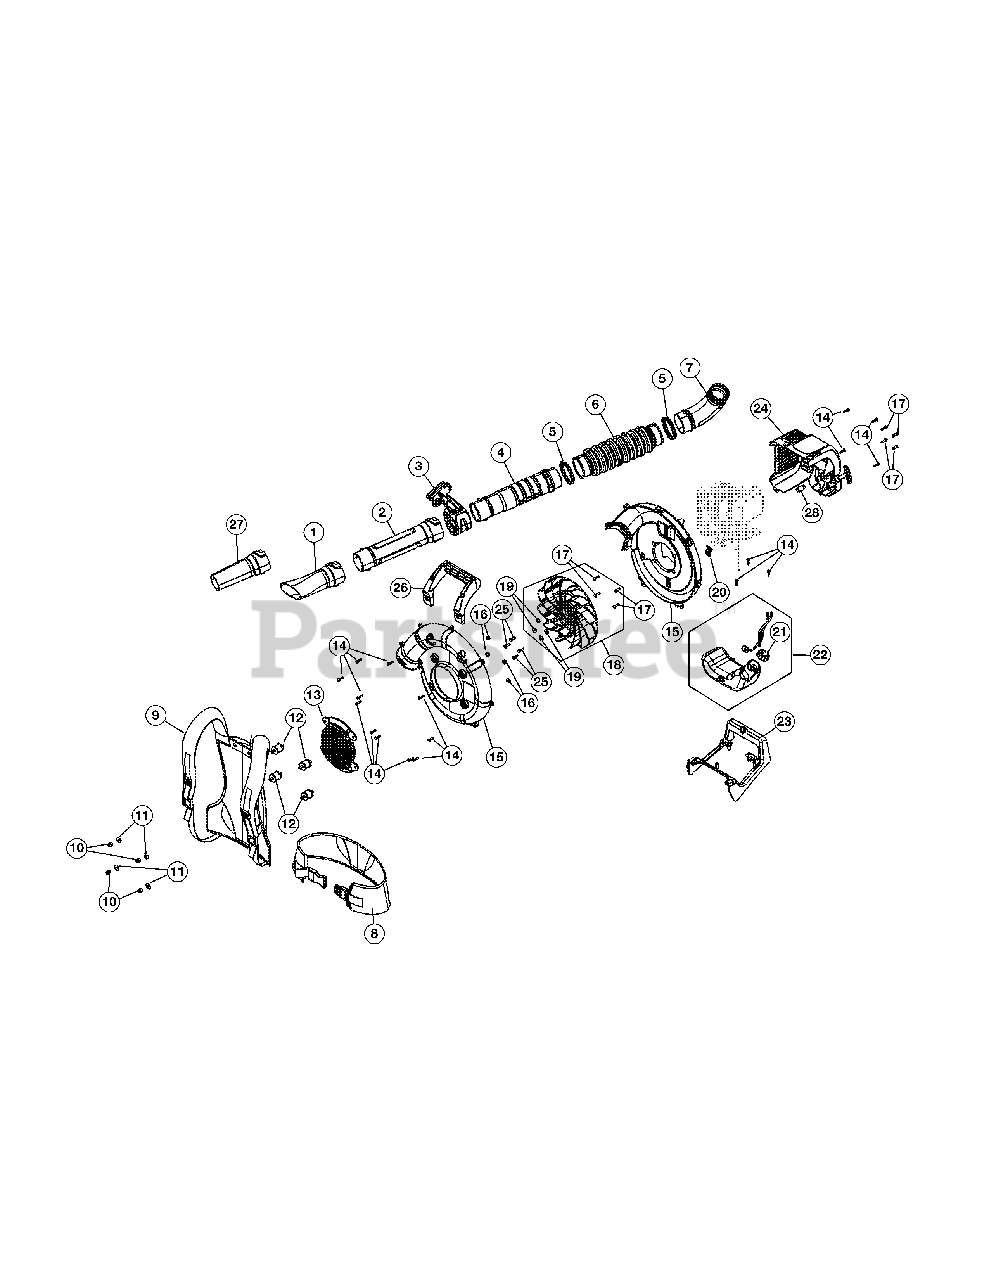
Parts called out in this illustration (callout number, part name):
1	Flared Nozzle
2	Lower Blower Tube
3	Throttle Grip Assembly
4	Upper Blower Tube
6	Flex Tube
7	Elbow Tube
8	Hip Belt
9	Support System
10	Nut
11	Washer
12	Isolator Mount
13	Intake Cover
15	Impeller Housing Assembly
16	Nut
17	Housing Screw
18	Impeller (Incl. Ref No. 19 & 25)
20	Throttle Retaining Clip
21	Fuel Cap
22	Fuel Tank Assembly (Incl. Ref No. 21)
24	Engine Cover Assembly
25	Impeller Screw
27	Concentrator Nozzle
28	Electric Starter Adapter
